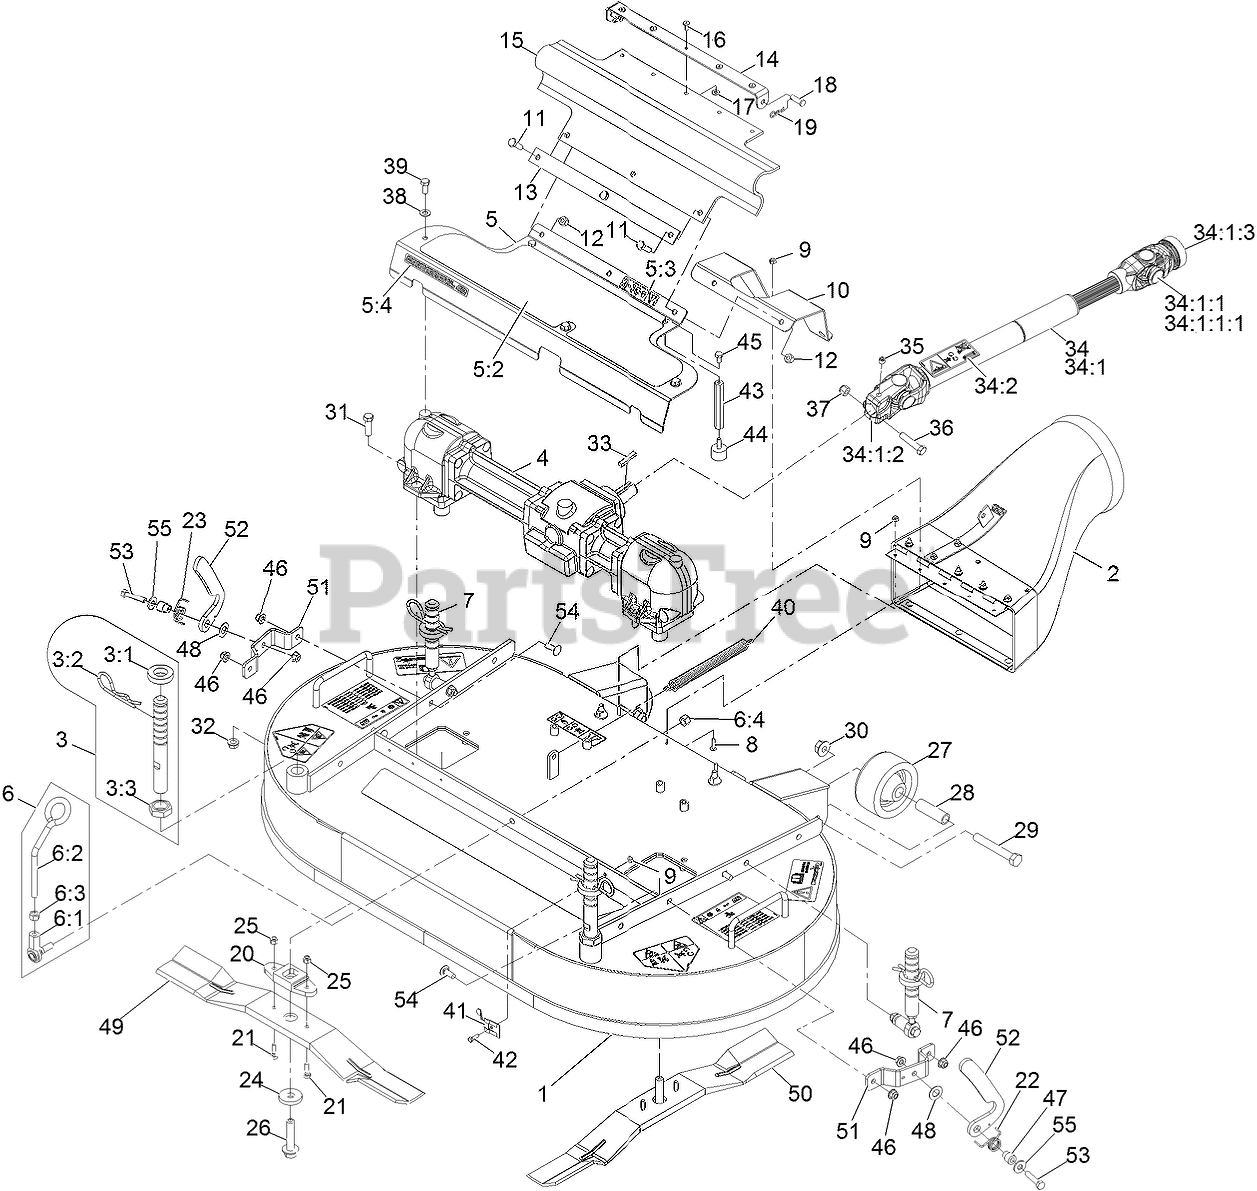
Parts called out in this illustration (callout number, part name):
1	Deck-Cutting 42 W/Decals
2	DISCHARGE TUBE ASM
3	FRONT DECK HEIGHT ADJUST
3:1	SPACER-DECK SUPPORT
3:2	PIN-CUT HEIGHT
3:3	NUT-JAM
4	GEARBOX ASM
5	ASM,GEARBOX COVER 42 W/DE
5:2	PAD-ANTI SKID
5:3	DECAL-DANGER
5:4	Decal-Commercial 42
6	DECK LATCH ASM
6:1	BALLJOINT-RH
6:2	LATCH-DECK
6:3	NUT-HEX
6:4	NUT-LOCK
7	REAR DECK HEIGHT ADJUST A
8	SCREW-HEAD, TRUSS
9	NUT-LOCK, NI
10	GUARD-DRIVE SHAFT
11	SCREW-HH
12	NUT-LOCK, NI
13	STRAP-DRIVE, LINE COVER
14	BRACKET-GUARD, PTO
15	GUARD-PTO
16	RIVET-BLIND
17	WASHER-FLAT
18	PIN-CLEVIS
19	PIN-COTTER
20	DRIVER-BLADE
21	BOLT-SHEAR
22	Spring-Torsion, LH (Yellow)
23	Spring-Torsion, RH
25	NUT-LOCK, NI
26	BOLT-BLADE
27	ROLLER-DECK
28	SPACER-ROLLER
29	SCREW-HH
30	NUT-HHF
31	SCREW-HH
32	NUT-HHF, WHIZ
33	KEY-SQUARE
34	DRIVE SHAFT ASM
34:1	Drive Shaft-Telescoping
34:1:1	U-JOINT KIT
34:1:1:1	FITTING-GREASE
34:1:2	YOKE-KEYED
34:1:3	YOKE-QUICK DISCONNECT
34:2	DECAL-DANGER, DRIVELINE
35	SCREW-SET, HSH
36	SCREW-HH
37	NUT-LOCK, NI
38	WASHER-PLAIN
39	SCREW-HH
40	SPRING-EXTENSION
41	CLIP-DECK, HOLD UP ROD
43	STAND-OFF
45	SCREW-HH
46	NUT-HF, NI
47	Collar-Basket
48	Washer-Plastic
49	BLADE,22 INCH RH
50	BLADE,22 INCH LH
51	Bracket-Latch Pivot
52	Latch - Deck
53	SCREW-HH
54	BOLT-CARR
55	WASHER-FLAT
